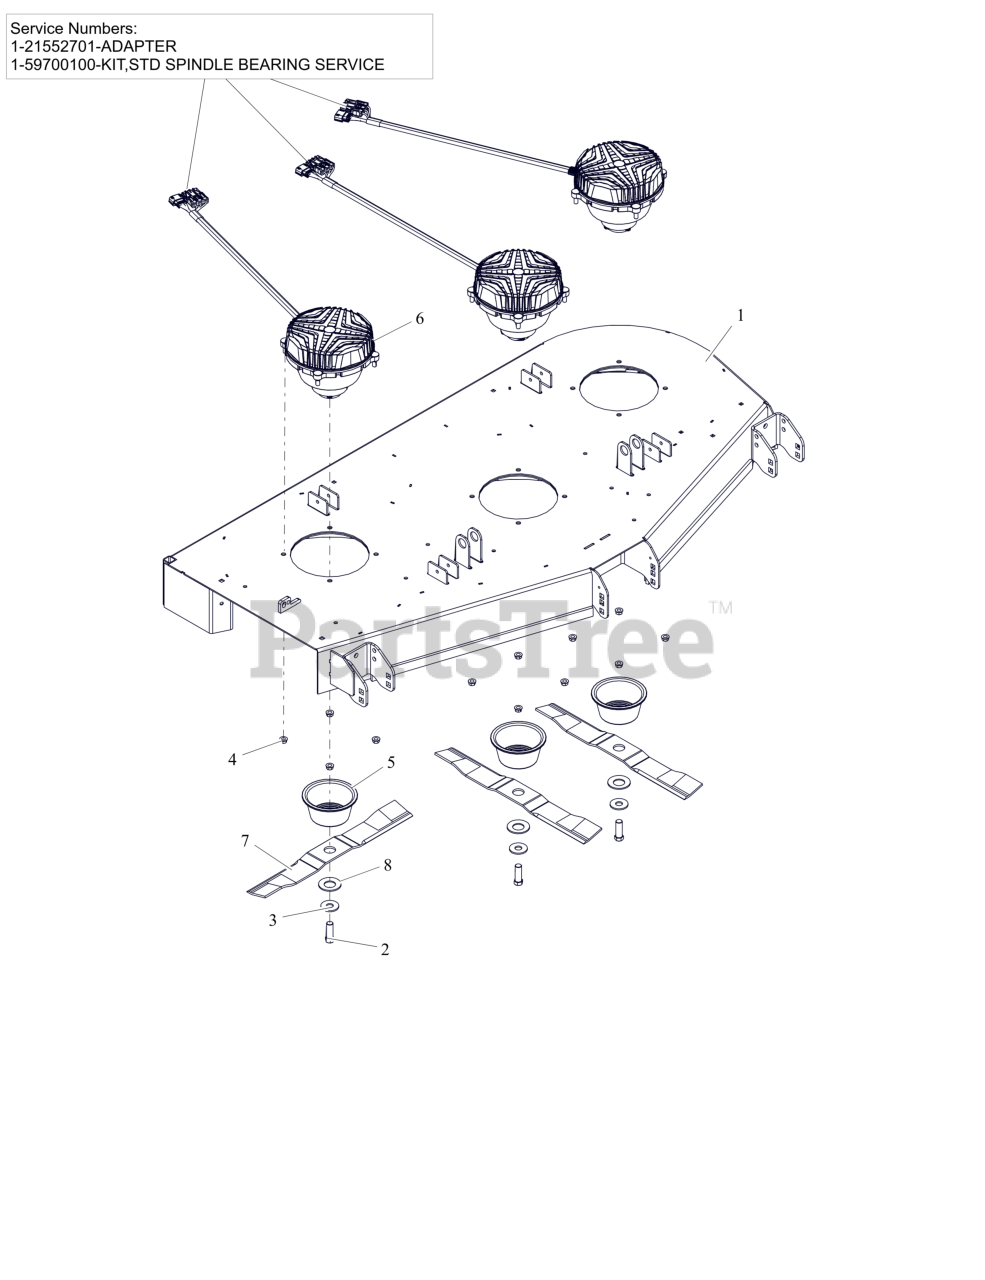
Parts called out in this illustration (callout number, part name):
1	KIT,DECK-60E W/DECALS-ARIENS
2	BLT, HEX .62-18X1.75 G8 ZCC
3	WSHR, HRDN 0.687X1.75X0.134 HRD
4	NUT-LK-CTR-FLG .375-16 GF ZCC
5	GUARD, SPINDLE LOWER
6	MOTOR, SPINDLE-CW
6	ADAPTER
6	KIT,STD SPINDLE BEARING SERVICE
7	BLADE, MOWER 20.5"
8	WSHR, BLVL - .56X28.5X3 PHOS.COAT
